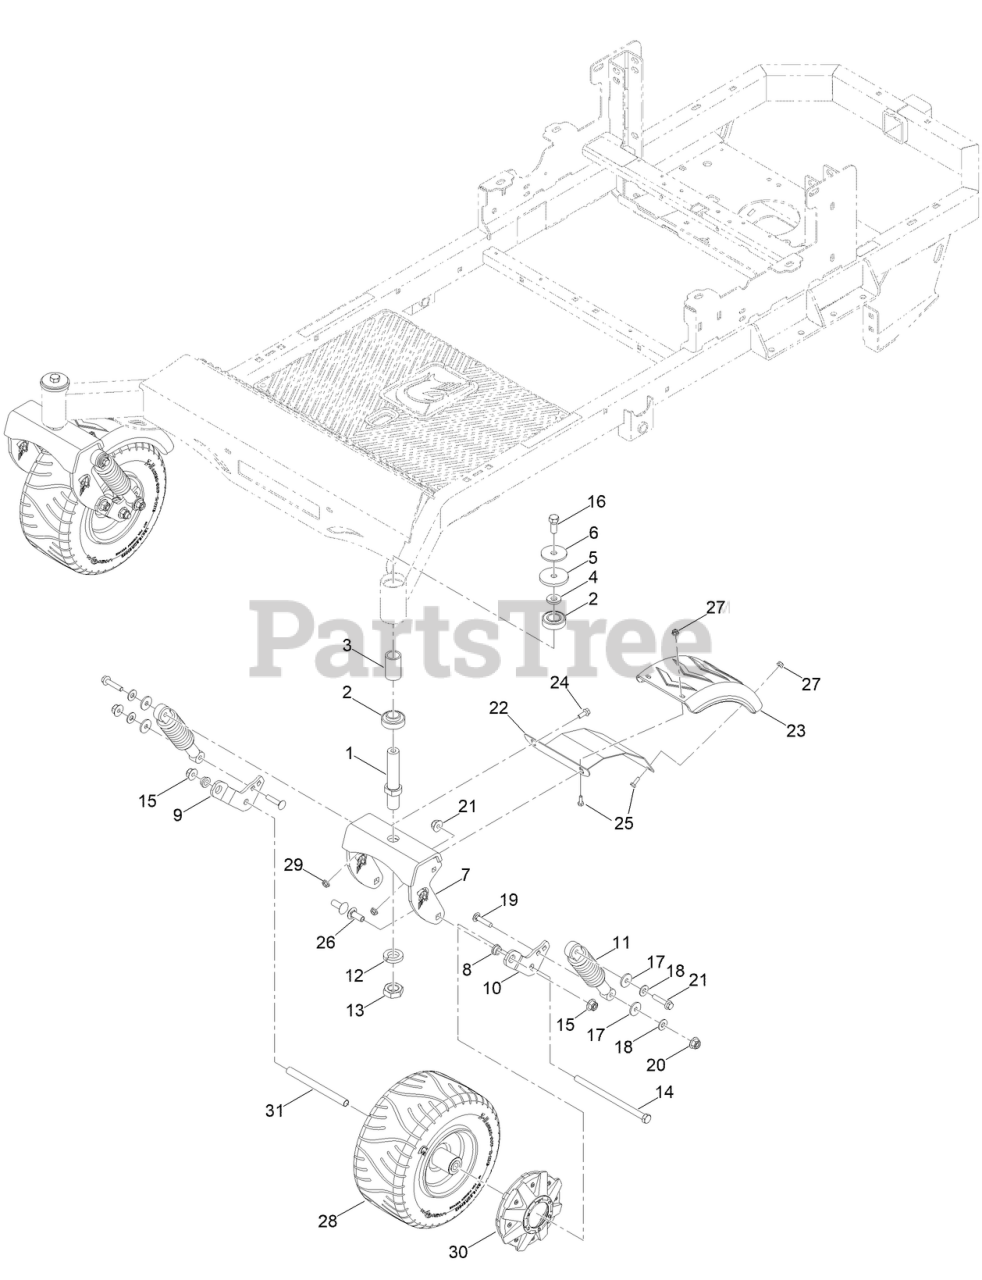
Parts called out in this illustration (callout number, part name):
1	MWR CASTER SHAFT
2	BEARING-BALL
3	CASTER FORK SHAFT BEARING SPACER
4	1/2 FENDER WASHER 1-1/4IN OD ZINC
5	FT HUB PLASTIC WASHER
6	MWR CASTER SHAFT WASHER
7	2022 FT FORK SHOCK ASSY
8	1/2IN ID X 3/4IN OD X 3/8IN FLANGE BUSH
9	2022 SRT TWEELS SUSP BRKT RT PAINTED
10	2022 SRT TWEELS SUSP BRKT LT
11	2020 RZ PRO SEAT / FT FORK SHOCK
12	1IN L/W MED SPLIT ZC
14	1/2-13 X 8-1/2 HEX C/S GR 5 ZINC YELLOW
15	NUT-LOCK
16	1/2-20 X 1-1/4 HEX FLANGE BOLT GR 8 YZ
17	FLT WASHER 1.25ODX.38IDX.125 THK PLA
18	WASHER-FLAT
19	3/8IN-16X1-3/4IN G8 CARRIAGE BOLT
20	3/8-16 NYLON INSERT FLANGE L/NUT YZ
21	3/8-16 X 1-.75 HEX FLG BOLT GR 8 YELLOW
22	2020 SPARTAN FT FENDER BRKT PAINT
23	SPARTAN FORK FT FENDER
24	SCREW-HHF
25	SCREW-HH
26	1/2-13 X 1.25 CARRIAGE BOLT YELLOW
28	SPARTAN RADIAL FT TIRE AND WHEEL ASSM
29	NUT-HF
30	MWR FT WHEEL HUB CAP
31	MWR FT WHEEL SPANNER
